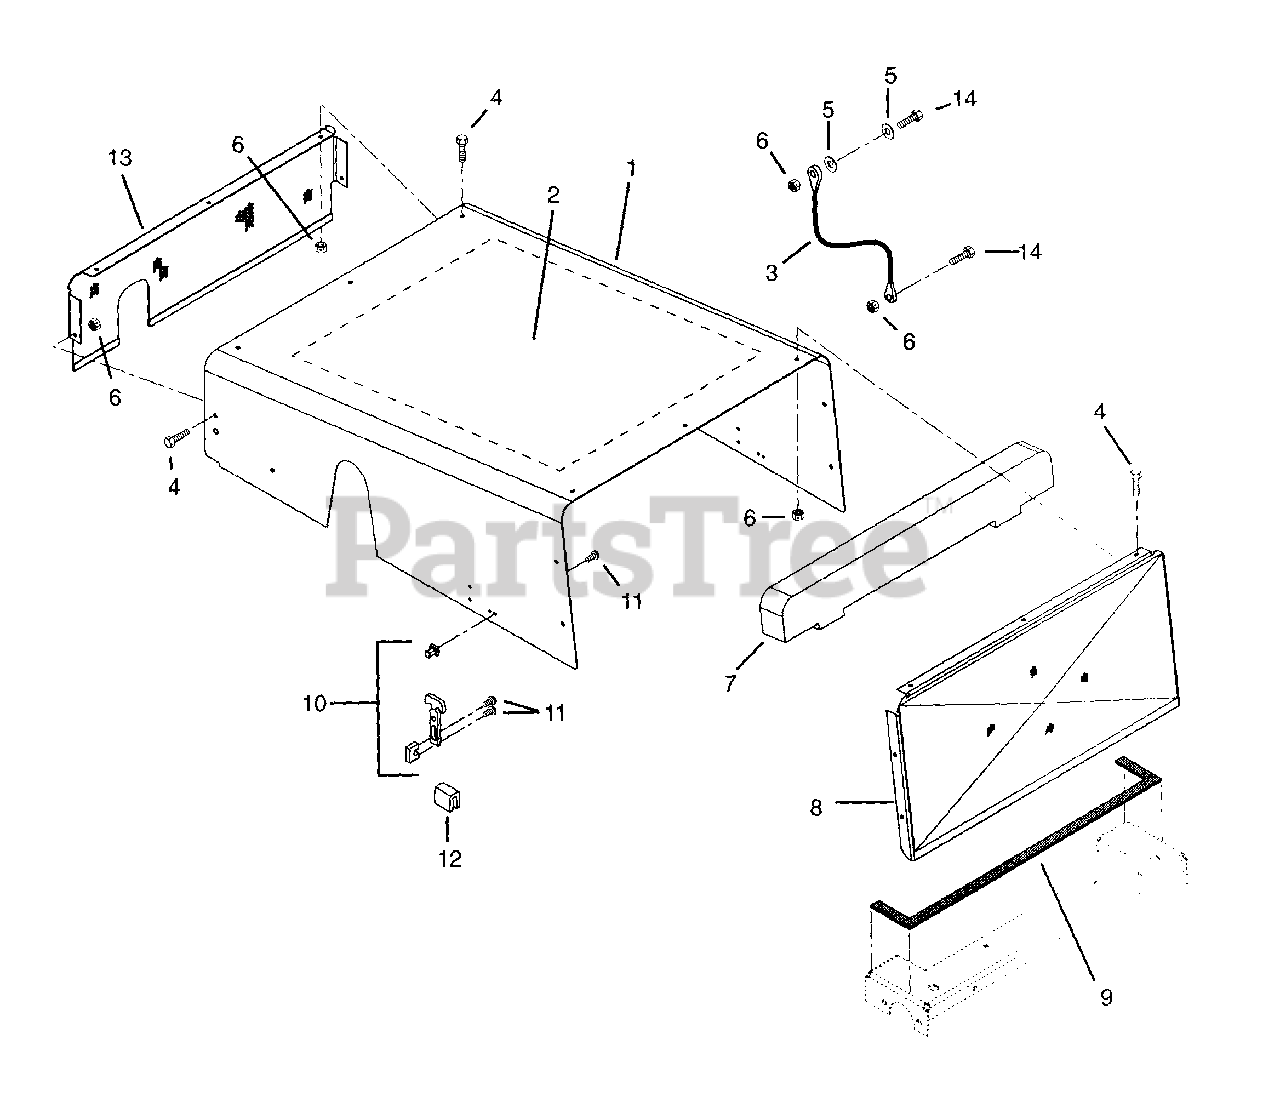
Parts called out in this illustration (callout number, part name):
1	Hood
2	Sound Panel
3	Cable, Hood
4	Screw-Machine .25-20 x .50 TXTR
5	Washer-Flat-Steel .312 x .734 x .065
6	Nut-Locking-Center .25-20
7	Foam, Hood
8	Hood, Front Screen
9	Foam Tape 1/4 x 3/4
10	Latch, Rubber
11	Screw-Machine 10-24 x .50 Hex Washer Head
12	Strip, Cowl
13	Screen, Rear
14	Bolt-Hex .25-20 x .75 Grade 5
